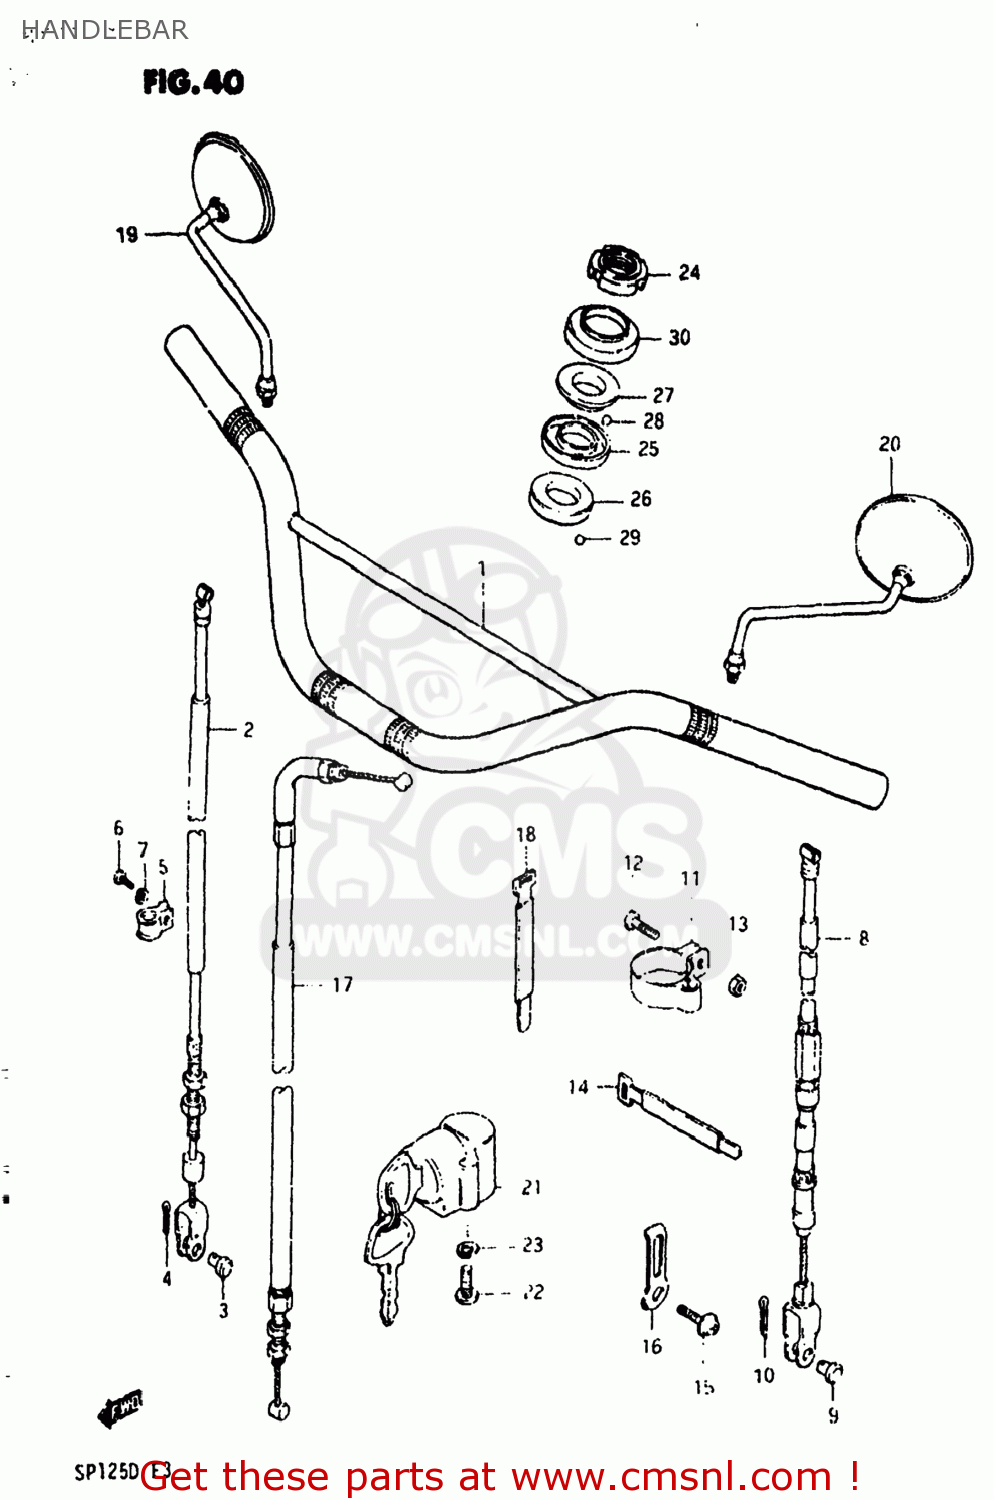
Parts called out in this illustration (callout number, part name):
1	HANDLEBAR
2	CABLE,FRONT BRAKE
3	PIN(L:17.5)
4	PIN
5	CLAMP,FR BRAKE CABLE
6	SCREW 6X12
7	LOCK WASHER
8	CABLE ASSY,CLUTCH
9	PIN(L:15)
10	PIN
11	CLAMP,CABLE
12	SCREW
13	NUT
14	CLAMP
15	SCREW
16	CLAMP,CABLE
17	CABLE ASSY,THROTTLE
18	CLAMP
19	MIRROR ASSEMBLY,RIGHT
20	MIRROR ASSEMBLY,LEFT
21	LOCK ASSY,STEERING
22	SCREW
23	LOCK WASHER
24	NUT,STEERING STEM(25X44X10)
25	RACE,STEERING INNER UPR
26	LACE,STEERING INNER LWR
27	RACE,STEERING OUTER UPR
28	BALL
29	BALL
30	DUST SEAL,STEERING UPR
